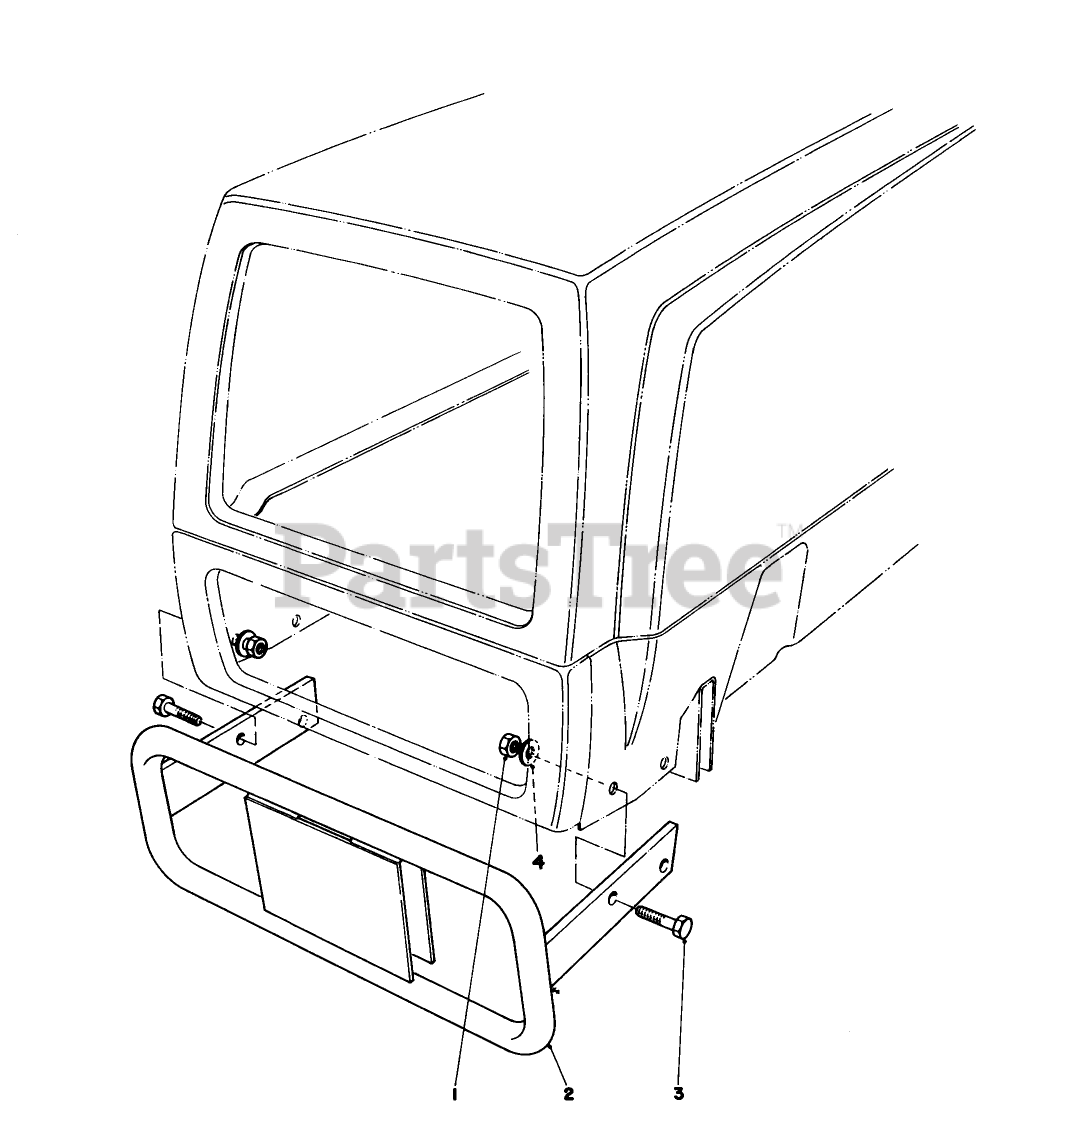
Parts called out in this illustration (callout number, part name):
1	NUT-LOCK, CONE
2	Bumper W.A.
3	SCREW-HH
4	WASHER-PLAIN
